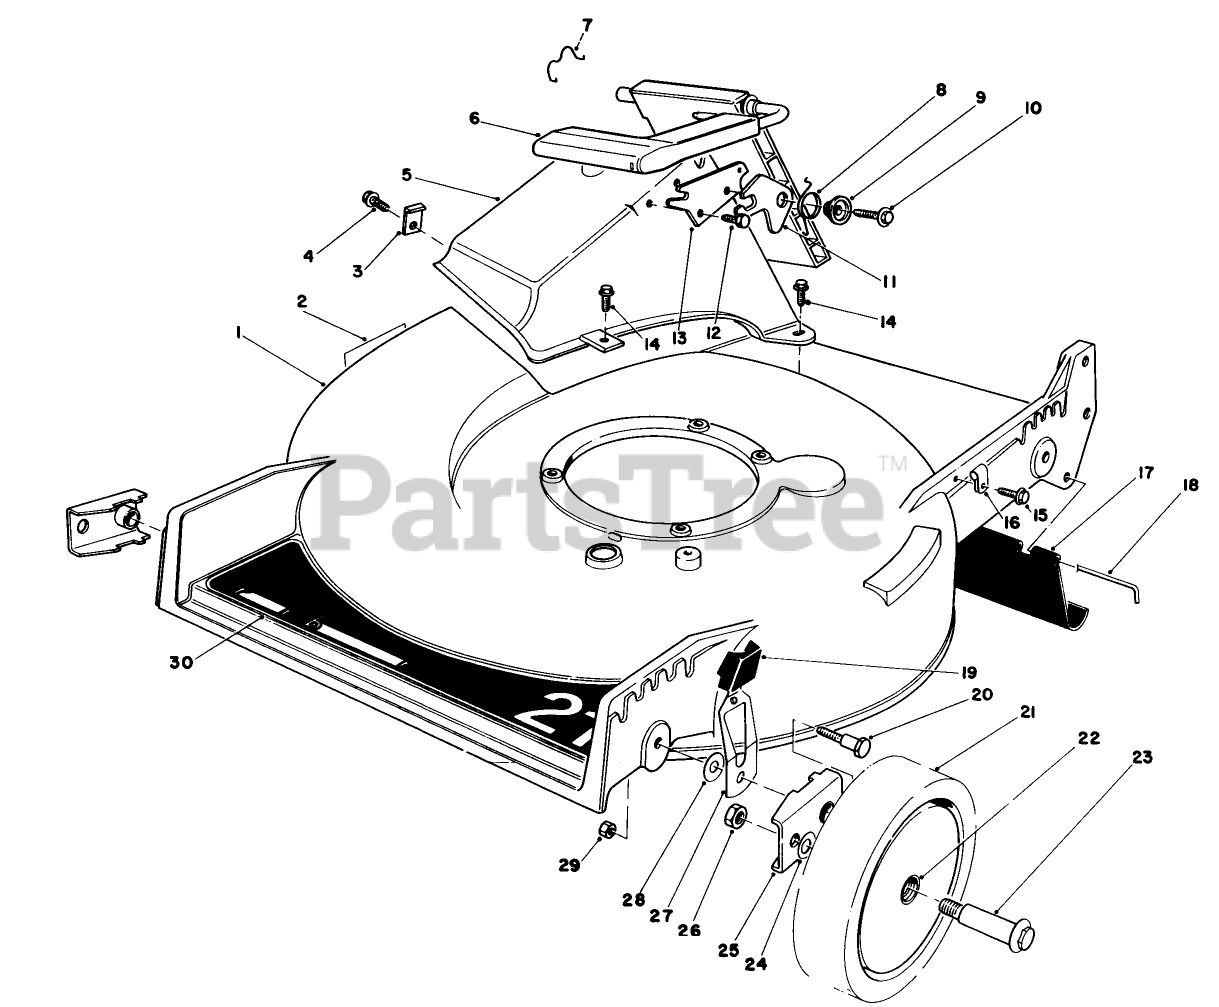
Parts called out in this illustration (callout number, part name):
1	21HP RB-SUZ HSG/DECAL
2	DECAL-DANGER
3	TUNNEL CLIP
4	SCREW
7	DOOR RET SPRING
8	TORSION SPRING
9	DOOR SPACER
10	SCREW-HWH
11	SAFETY LATCH
12	SCREW-PLASTITE
13	DOOR LATCH PLATE
14	SCREW-HWH
15	SCREW
16	CLAMP-CABLE
18	ROD-SHIELD
19	KNOB-ARM
20	PIVOT SCREW
22	BUSHING
23	WHEEL BOLT
24	WASHER
25	HP PIVOT ARM ASM
26	NUT-LOCK
28	WASHER-PIVOT
29	NUT-LOCK, NI
